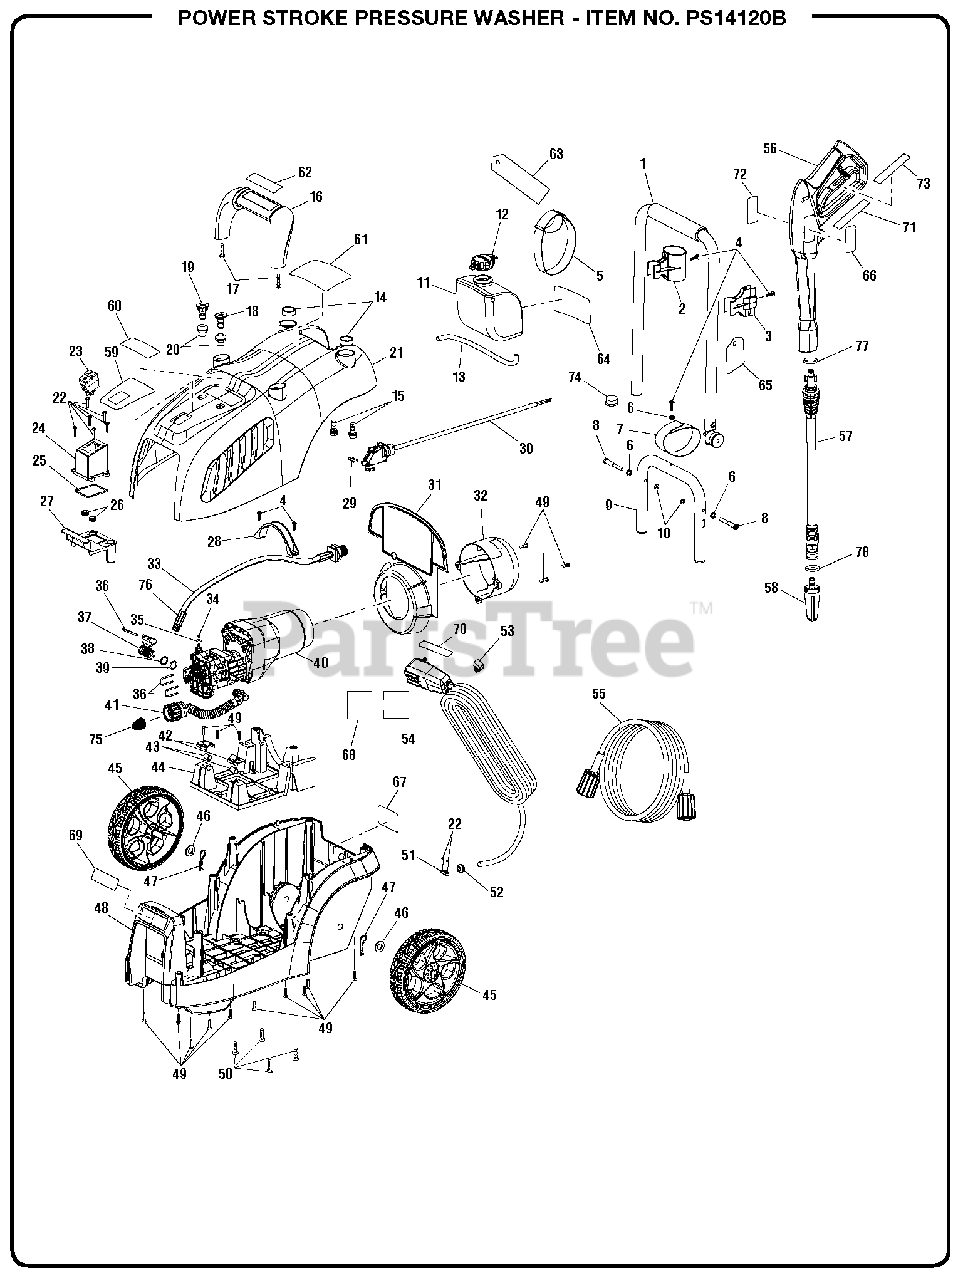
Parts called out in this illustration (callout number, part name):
1	Handle Assembly
2	Trigger Handle Holder
3	Wand Holder
4	Screw (M4.2 x 16 mm)
5	Velcro Strap (For Hose)
6	Washer (ID8 x OD12 x 2.5t)
7	Velcro Strap (For Power Cord)
8	Shoulder Bolt (M6 x 52.5 mm)
9	Lower Handle
11	Soap Tank
12	Soap Tank Cap
13	Chemical Siphon Tube
14	Lower Handle Ring
15	Bolt (M8 x 20 mm)
16	Assist Handle
17	Screw (M5.5 x 30 mm)
18	Soap Nozzle (Blue)
19	15deg Nozzle
20	Nozzle Grommet
21	Upper Housing
22	Screw (M3.5 x 16 mm)
24	Switch Box
25	Switch Seat Gasket
27	Switch Bracket
28	Motor Strap
30	Switch Assembly (Total Stop Switch)
31	Heat Shield
32	Air Funnel
33	Water Outlet Assembly
34	O-Ring (ID2.9 x 1.8t)
35	Washer (Brass)
37	Outlet Connector
38	Backup Ring
39	O-Ring (ID14 x 2t)
40	Pump and Motor Assembly
41	Water Inlet Hose Assembly
42	Clamp plate
43	Shock Absorber
44	Motor Support Board
45	Wheel Assembly
47	Cotter Pin
48	Lower Housing
49	Screw (M4.2 x 16 mm)
50	Screw (M5.5 x 20 mm)
51	Cord Clamp
52	Grommet (Housing)
53	Cord Clip
54	Power Cord
55	High Pressure Hose
56	Trigger Handle
57	Spray Wand
58	Turbo Nozzle
59	Performance Label
60	Nozzle Selection Guide
61	Warning Label (Fr/Sp)
62	Handle Logo Label
63	Warning Hangtag
64	Quick Start Label
65	Nozzle Hang Tag
66	Warning Label (Eng)
67	Data Label
68	Warning Label (Cord Wrap)
69	Front Logo Label
70	Power Cord Label
71	Trigger Handle Warning Label
72	Logo Label (Spray Wand)
73	Trigger Handle Rating Label
74	Handle Foot Cap
75	Inlet Filter
76	Outlet Connector Nut
77	O-Ring (ID8 x 2t)
78	O-Ring (ID9.5 x 2.6t)
